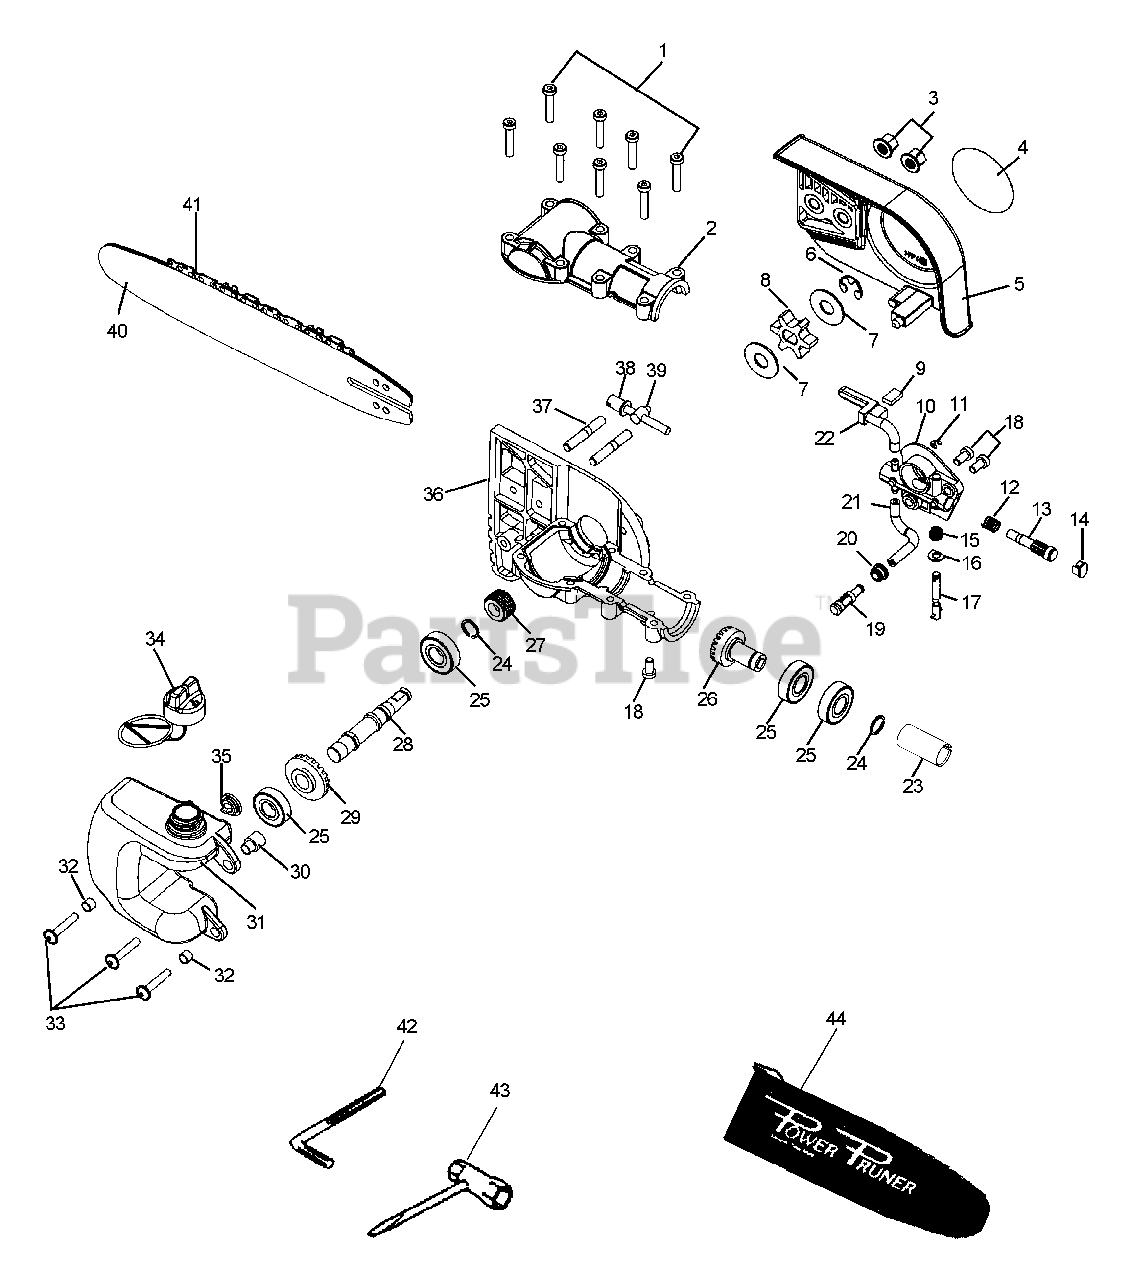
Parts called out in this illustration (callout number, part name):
1	SCREW - 5X25
2	CASE, GEAR - UPPER
3	NUT - 6 -- FLANGE
4	LABEL - ECHO
5	GUARD, SPROCKET
6	RING, RETAINING
8	SPROCKET, DRIVE
9	PAD, FOAM
10	AUTO-OILER ASSY
11	RING, RETAINING
12	SPRING, PLUNGER
13	PLUNGER ASSY
14	CAP, OIL PUMP
17	NEEDLE, ADJUST
18	SCREW - 5X10
19	FILTER, OIL
20	GROMMET
21	PIPE - 3X6X75 -- BLACK
22	PIPE, OIL OUTLET
23	COLLAR - 22
24	RING, RETAINING - 12
25	BEARING, BALL - 6001
26	GEAR - BEVEL
27	GEAR - WORM
28	GEAR - SHAFT
29	GEAR - BEVEL
31	TANK, OIL
33	SCREW - 5X20
34	CAP ASSY
36	CASE, GEAR - LOWER
37	STUD - 6
38	SCREW, TENSIONER
39	TENSIONER, CHAIN
40	GUIDE BAR - 10" (25cm)
41	SAW CHAIN - 10" (25cm)
42	HEX KEY
43	T-WRENCH
44	COVER, GUIDE BAR
